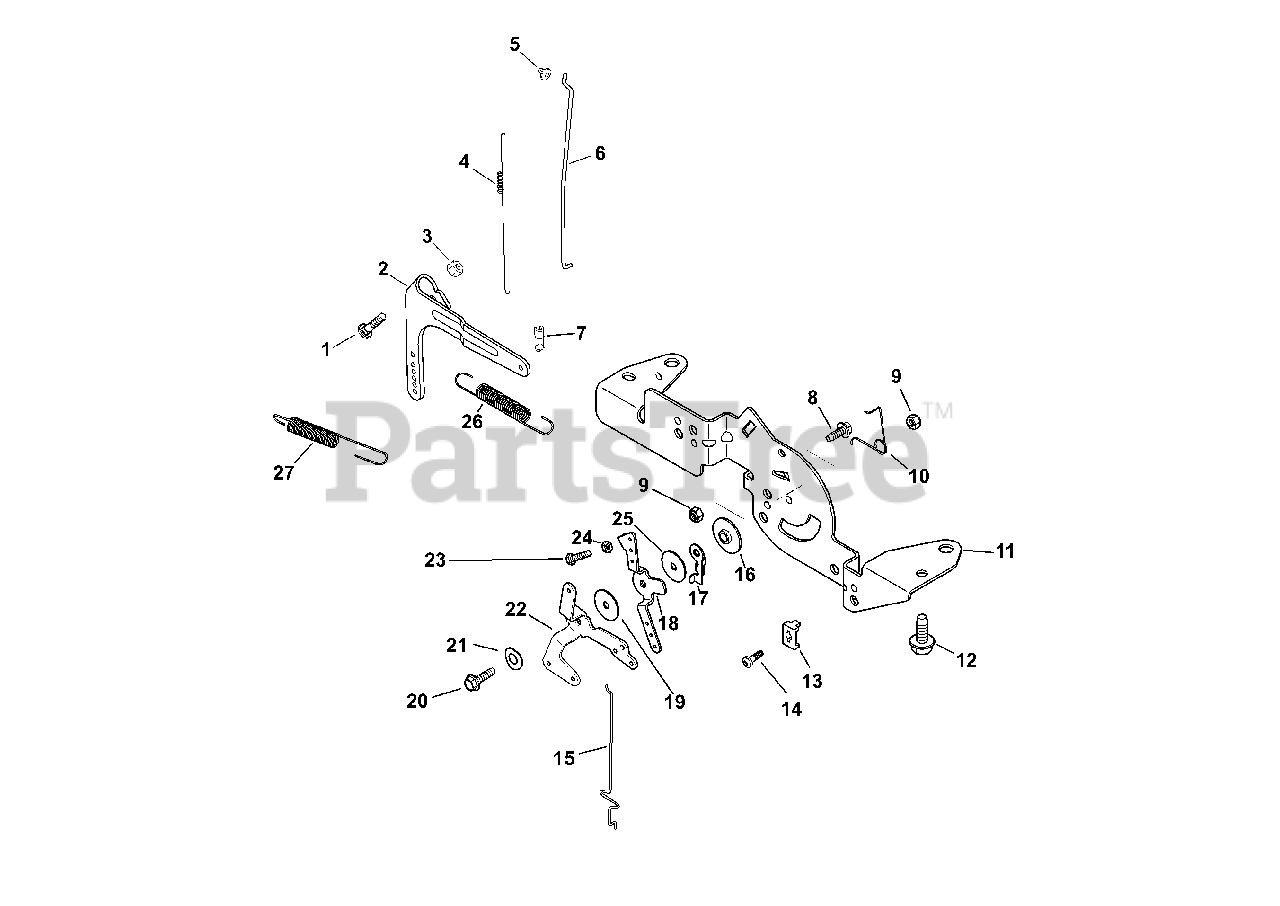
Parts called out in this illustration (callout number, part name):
1	Rd. Hd. Sq. Neck Bolt, M6 x 1.0 x 25
2	Governor Lever
3	Flg. Nut, M6 x 1.0
4	Linkage Spring
5	Linkage Retaining Bushing
6	Throttle Linkage
7	Throttle Linkage Bushing
8	Screw, M5 x .8 x 16
9	Lock Nut, M5 x .8
10	Choke Return Spring
11	Control Bracket
12	Flg. Thd. Frm. Screw, M6 x 1.0 x 16
13	Cable Clamp
14	Lbd. Thd. Frm. Screw, M5 x 0.8 x 16
15	Choke Linkage
16	Control Assembly Spacer
17	Throttle Actuator Lever
18	Throttle Control Lever
19	Flat Washer, 5.5MM
20	Screw, M5 x .8 x 20
21	Spring Washer, 1/4"
23	Screw, M4 x .7 x 25
25	Flat Washer, 5MM
26	Governor Spring
27	Governor Spring
